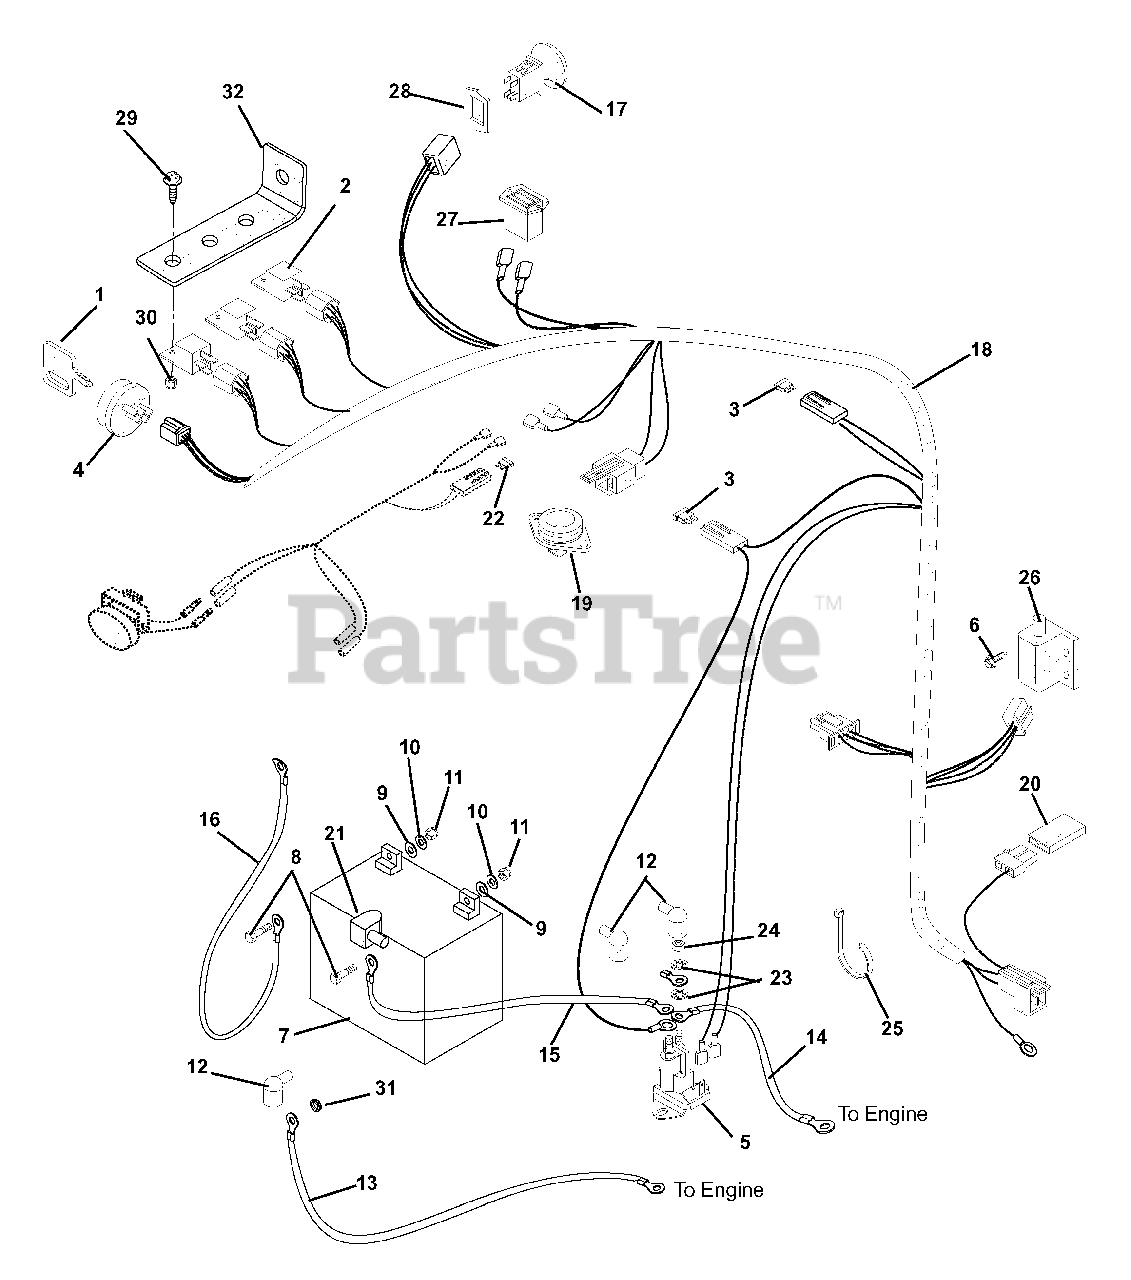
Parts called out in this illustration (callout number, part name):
1	KEY -W/CAP
2	RELAY
3	FUSE-25 AMP ATC TYPE
4	KEY SWITCH
5	SOLENOID
6	@SCR-TAP 10-24X.50 HWH TR YWZC
7	BATTERY, 300 CCA 10U1L
7	BATTERY W/ TUBE
8	@BLT-HEX .25-20X.75 GR5 YWZC
9	@WSHR-FL-STL.281X.62X.065 YWZC
10	@WSHR-LK .25X.062 REG YWZC
11	@NUT-HEX .25-20 YWZC
12	BOOT, EYELET TERMINAL
13	START CABLE 22"
14	STARTER CABLE 6.75"
15	STARTER CABLE 16"
16	GROUND CABLE .31X22.00X.31
17	SWITCH, CLUTCH
18	WIRE HARNESS, ZT XL/ZOOM CE
19	SWITCH- SNAP MTG N.O.
20	DIODE, CONNECTOR SHELL
21	INSULATOR
22	FUSE 20AMP
23	WSHR-LOCK INT .31 YWZC
24	NUT-JAM .31-24 YWZC
25	CABLE TIE LG 5-1/2
26	SWITCH- DOUBLE POLE N.O./N.O.
27	HOURMETER-QUARTZ 80VDCMAX
28	SHIM,PTO SW (DELTA #972301)
29	@SCR-MCH 10-24X.50 HWH YWZC
30	@NUT-LK-NYL 10-24 W/INSRT YWZC
31	GROMMET 1.0ID X 1.38 OD
32	BRACKET, RELAY
